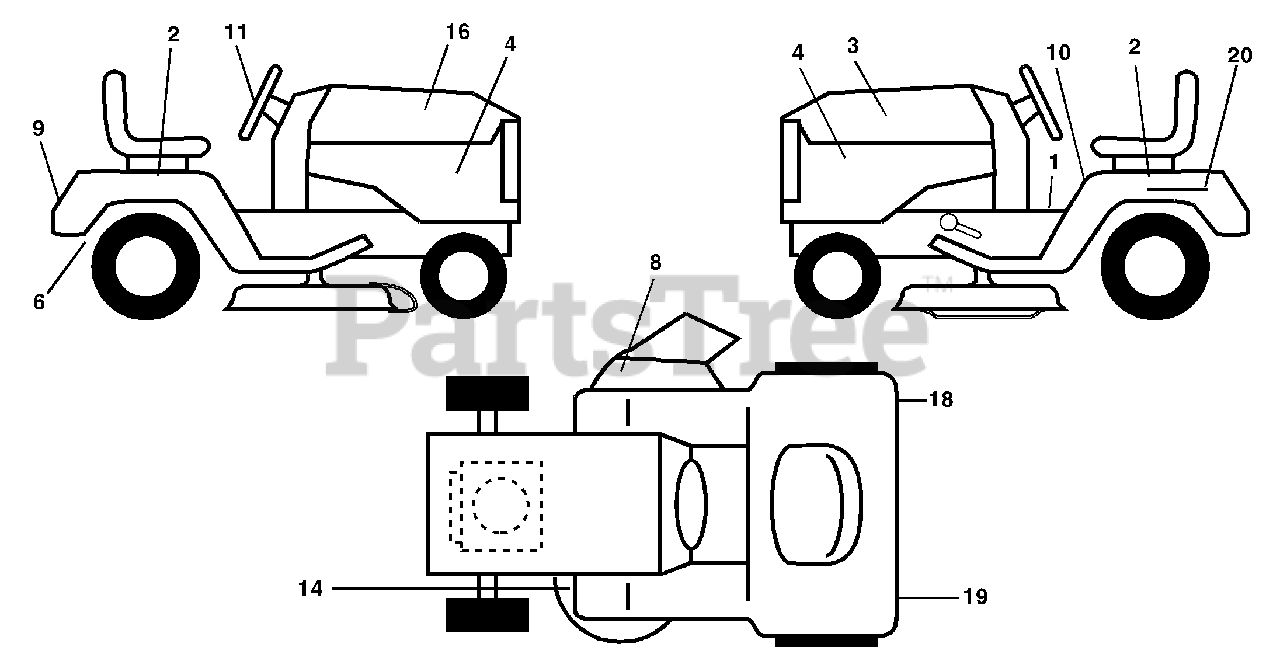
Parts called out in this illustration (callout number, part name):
1	Decal Oper
2	Decal Fender Auto
3	Decal Hood LH
4	Decal Side Panel Logo
6	Decal By Pass Lt Hydro
8	Decal Mower Warn Keep Hand Away
9	Decal Fender Logo
10	Decal Fender Danger E/F
11	Decal Ins Strg Whl
14	Decal V-Belt Schematic
16	Decal Hood Rh
18	Decal Fend Reflector RH PPRO
19	Decal Fend Reflector LH PPRO
20	Decal Bat Dan/Psn
